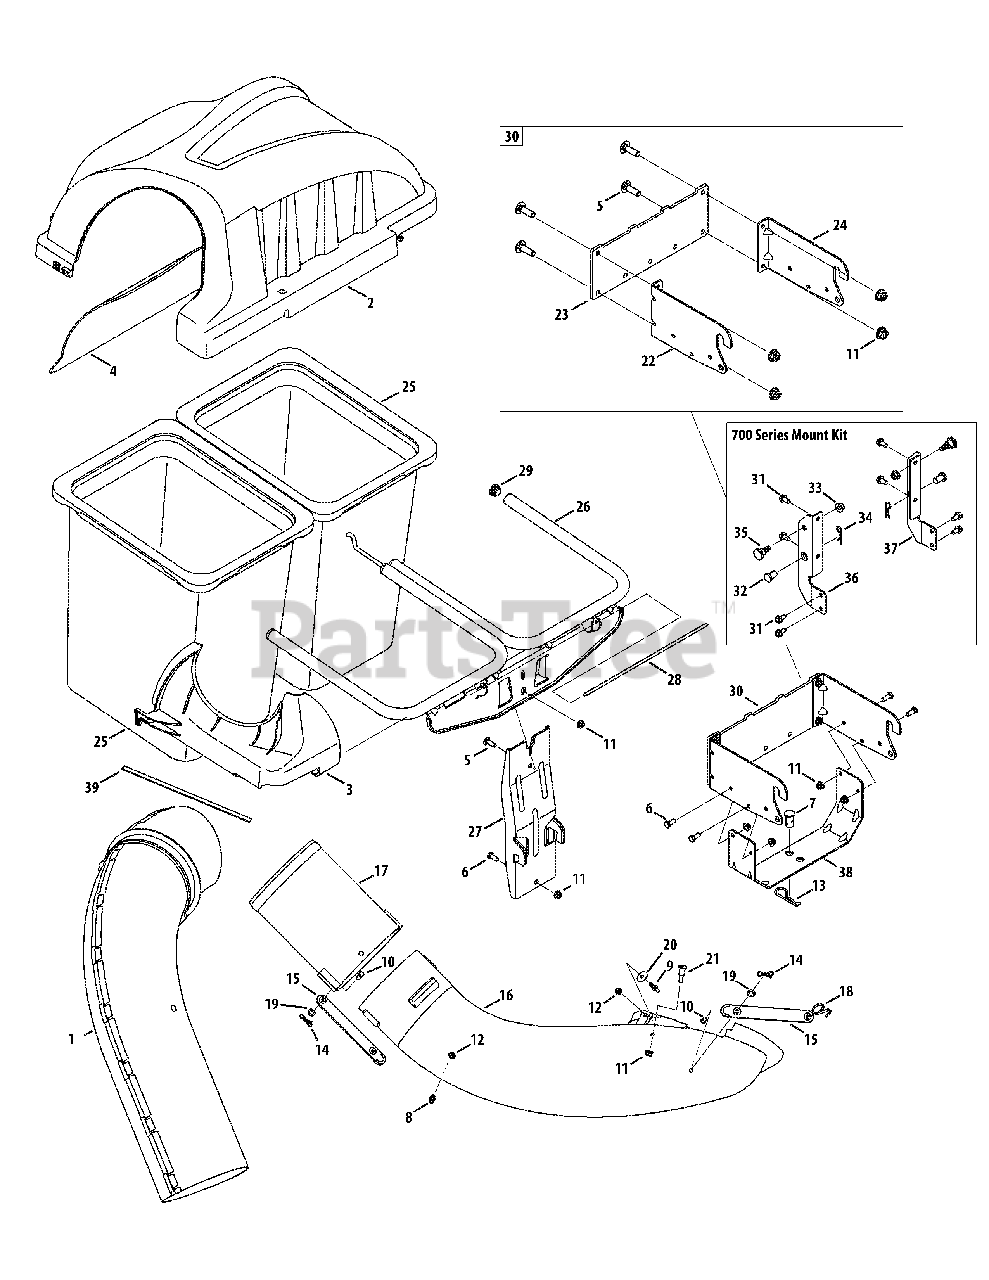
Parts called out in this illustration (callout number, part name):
1	Upper Chute Assembly
2	Double Bagger Cover Assembly
3	Upper Chute Support
4	Bagger Cover Screen
5	Carriage Screw, 5/16-18 x 1.00"
6	Hex Head Screw, 5/16-18 x .75"
7	Clevis Pin, .62" Dia.
8	Grass-catcher Pin, 1/4-20
9	Attachment Pin, 1/4 x 0.66 Lg.
10	Clevis Pin, 5/16 x .75 Lg.
11	Flange Lock Nut, 5/16-18
12	Lock Nut, 1/4-20
13	Internal Cotter Pin, .148 x 3.00
14	Bow-Tie Cotter Pin, 72
15	Chute Strap, 6.00 Lg.
16	Bagger Discharge Chute, Elbow
17	Bagger Chute Adapter, 7 In.
18	Torsion Spring Hook
19	Flat Washer, .344 x .62 x .033
20	Flat Washer, .265 x .938 x .120
21	Shoulder Screw, .437 x .54
22	Mounting Bracket, RH
23	Universal Mounting Bracket
24	Mounting Bracket, LH
25	Grass-bag Assembly
26	Double Bag Support Assembly
27	Vertical Support Bracket
28	Cover Hinge Pin
29	End Plug
30	Mounting Bracket Kit (Incl. ref. 22, 23, 24)
31	Tap Screw, 5/16-18 x .750
32	Clevis Pin, .50 x .78
33	Flange Lock Nut, 3/8-16
34	Click Pin, .092 x 1.64 Lg.
35	Shoulder Screw, .625 x .412
36	Mounting Bracket, RH
37	Mounting Bracket, LH
38	Universal Support Bracket
39	Self-Adhesive Foam Strip
